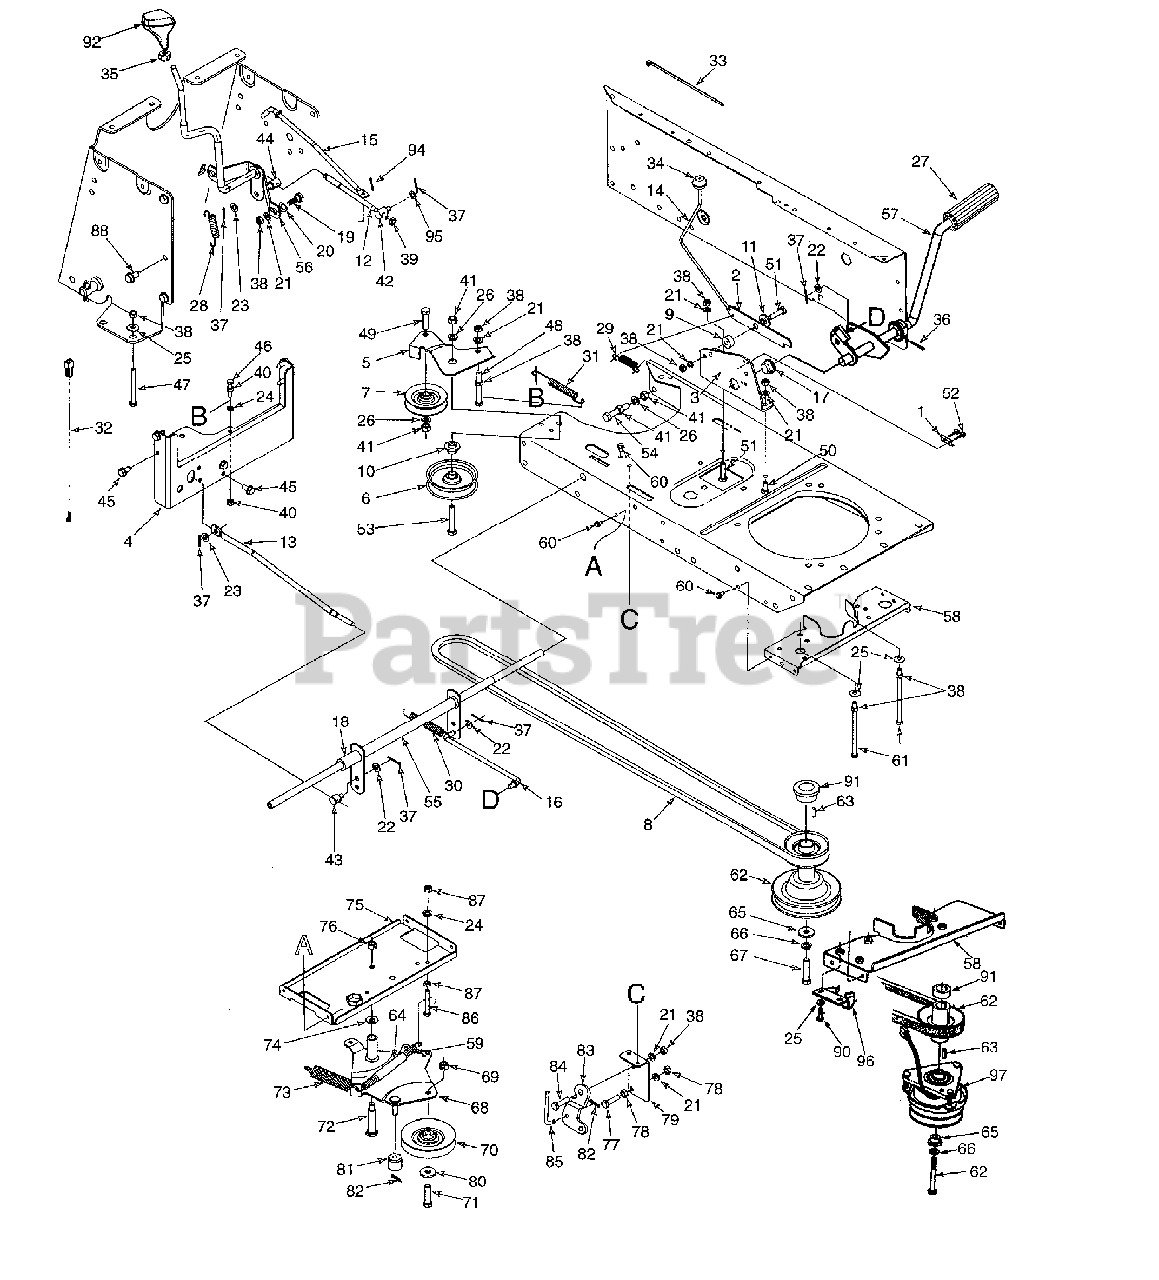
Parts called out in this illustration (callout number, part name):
1	Switch Plate
7	Idler Pulley
8	"V"-Belt
9	Spacer .34" I.D. x .44" Lg.
10	Shld. Spacer .38" I.D.
11	Shld. Spacer
12	Speed Selector Rod
13	Neutral Return Rod
14	Brake Lockout Rod
15	Hydro Disengagement Rod
16	Brake Link Rod
17	Hex Flange Bearing
18	Nyliner Flange Bearing
19	Shld. Bolt
20	Spr. Wash. 7/16" I.D.
21	L-Wash. 5/16" I.D.
22	Fl-Wash. 5/16" I.D.
23	Fl-Wash. .38" I.D.
24	L-Wash. 1/4" I.D.
25	Bell-Wash. .345" I.D.
26	L-Wash. 3/8" I.D.
27	Foot Pad
28	Ext. Spring 2.75" Lg.
29	Ext. Spring 2.51" Lg.
30	Ext. Spring 4.74" Lg.
31	Ext. Spring 4.97" Lg.
32	Transmission Wire
33	Cable Tie
34	Ball Knob
35	Hex Jam Nut 3/8-16 Thd. (Gr. 5)
36	Cotter Pin 1/8" Dia. x 1" Lg.
37	Cotter Pin 3/32" Dia. x 1" Lg.
38	Hex Nut 5/16-18 Thd. (Gr. 5)
39	Hex Jam Nut 5/16 Thd. L.H.
40	Hex Nut 1/4-20 Thd. (Gr. 5)
41	Hex Nut 3/8-16 Thd. (Gr. 5)
42	Ferrule 5/16-24 Thd. L.H.
43	Ferrule 5/16-18 Thd.
44	Ferrule 3/8-24 Thd.
45	Hex Wash. TT-Tap Scr. 5/16 x .75" Lg.
46	Hex Bolt 1/4-20 x 1.25" Lg.
47	Hex Bolt 5/16-18 x 3" Lg.
48	Hex Bolt 5/16-18 x 2.75" Lg.
49	Hex Bolt 3/8-16 x 1.5" Lg.
50	Hex Bolt 5/16-18 x .75" Lg.
51	Hex Bolt 5/16-18 x 1.25" Lg.
52	Hex HD Tapp Scr. #10-16 x .75" Lg.
53	Hex Bolt 3/8-16 x 2.25" Lg.
54	Hex Bolt 3/8-16 x 2" Lg. (Gr. 5)
57	Hydro Foot Pedal Ass'y.
60	Hex Wash. TT-Tap Scr. 1/4-20 x.5" Lg.
61	Hex Bolt 5/16-18 x 5.25" Lg.
62	Engine Pulley
63	Sq. Key 1/4 x 1.5" Lg.
64	Convoluted Conduit
65	Fl-Wash. .45" I.D. x 1.25"
66	L-Wash. 7/16" I.D.
67	Hex Bolt 7/16-20 x 1.5" Lg.
68	Idler Brkt. Deck Ass'y.
69	Hex Cent. L-Nut 3/8-24 Thd.
70	Idler Pulley
71	Hex Bolt 3/8-24 x 1.5" Lg.
72	Shld. Bolt .498" Dia. x 2.05"
73	Ext. Spring 6.12" Lg.
74	Bell-Wash. .38" I.D. x .88" O.D.
76	Hex Cent. L-Nut 3/8-16 Thd.
77	Hex Bolt 5/16-24 x 1.25" Lg.
78	Hex Nut 5/16-24 Thd. (Gr. 5)
79	Parking Brake Mtg. Brkt.
80	Fl-Wash. .40" I.D. x .875" O.D.
81	Spacer
82	Hairpin Clip
83	Deck Control Pivot Brkt.
84	Shld. Bolt .437" Dia. x .162"
85	Deck Control Rod
86	Hex Bolt 1/4-20 x 2" Lg.
87	Hex Nut 1/4-20 Thd.
88	Hex AB-Tap Scr. 5/16 x .75"
90	Hex Bolt 5/16-18 x .75" Lg.
91	Clutch Spacer
92	Shift Knob
94	Hairpin Clip
95	Fl-Wash. .344" I.D. x .75" O.D.
